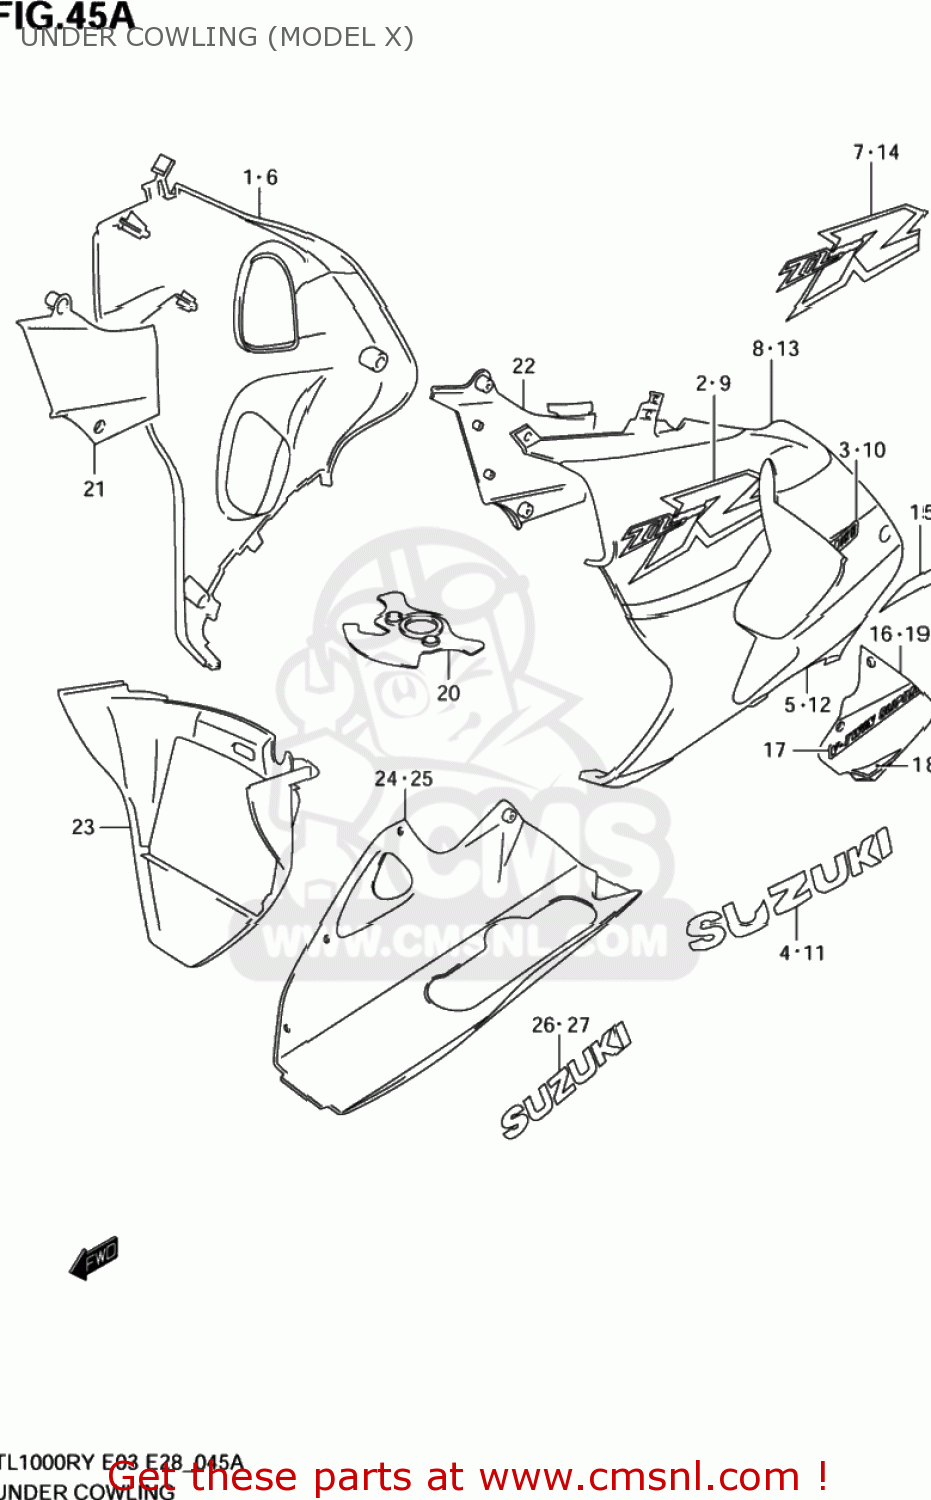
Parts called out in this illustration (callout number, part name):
1	COWLING ASSY,UNDER,R
2	EMBLEM,TL1000R
3	EMBLEM,UNDER,R
4	EMBLEM,SUZUKI,R
5	TAPE SET,UNDER,R
6	COWLING ASSY,UNDER,R
7	EMBLEM,UNDER COVER,R
8	COWLING ASSY,UNDER,L
9	EMBLEM,TL1000R
10	EMBLEM,UNDER,L
11	EMBLEM,SUZUKI,L
12	TAPE SET,UNDER,L
13	COWLING ASSY,UNDER,L
14	EMBLEM,UNDER COVER,L
15	TAPE,UNDER COWL,L(GRAY)
16	LID ASSY,UNDER,L
17	EMBLEM,LID,L
18	TAPE,LID LWR,L
19	LID,UNDER,L(BLACK)
20	COVER,LWR BRACKET
21	COWLING,UNDER INNER,R
22	COWLING,UNDER INNER,L
23	COWLING,UNDER CTR
24	COWLING,UNDER RR
25	COWLING ASSY,UNDER RR
26	EMBLEM,RR COWL,R
27	EMBLEM,RR COVER,L
